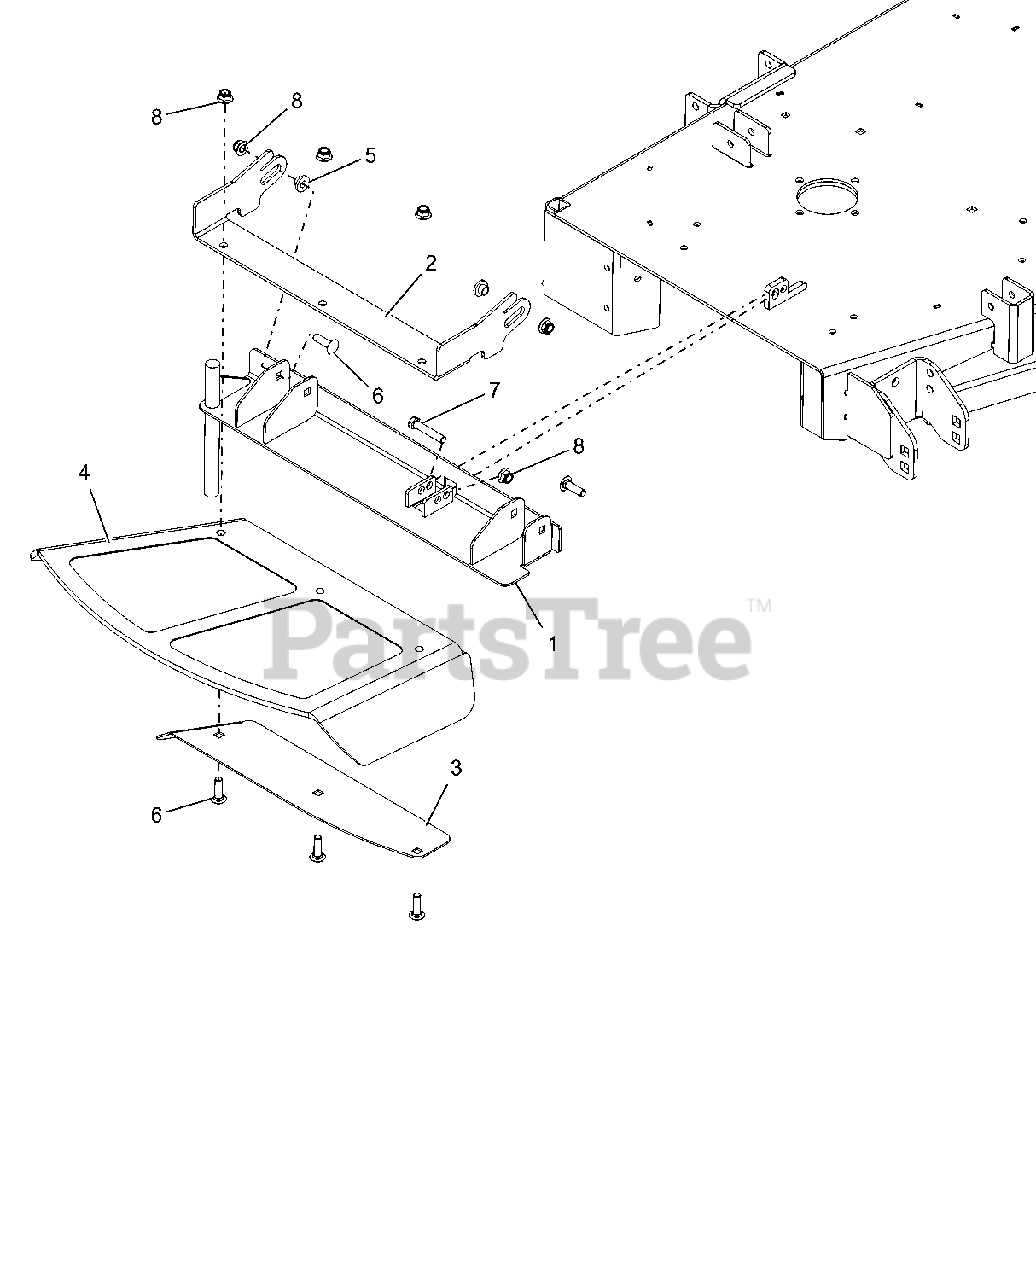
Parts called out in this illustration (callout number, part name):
1	WLDMT, 48-60" DISCH CHUTE MOUNT
2	BRKT, 48-60" CHUTE MTG (RED)
3	PLATE, 48-60" DISCH CHUTE CLAMP (RED)
4	CHUTE, 48-60" FORMED RUBBER DISCHARGE
5	BSHG, FLG .385 X .500 X .875 X .406
6	BLT-RHDSSQNK .38-16X1.25 G5YZ
7	BLT-HEX .38-16X2.00 GR5 YWZC
8	NUT-LK-NYL-FLG .38-16 YWZC
